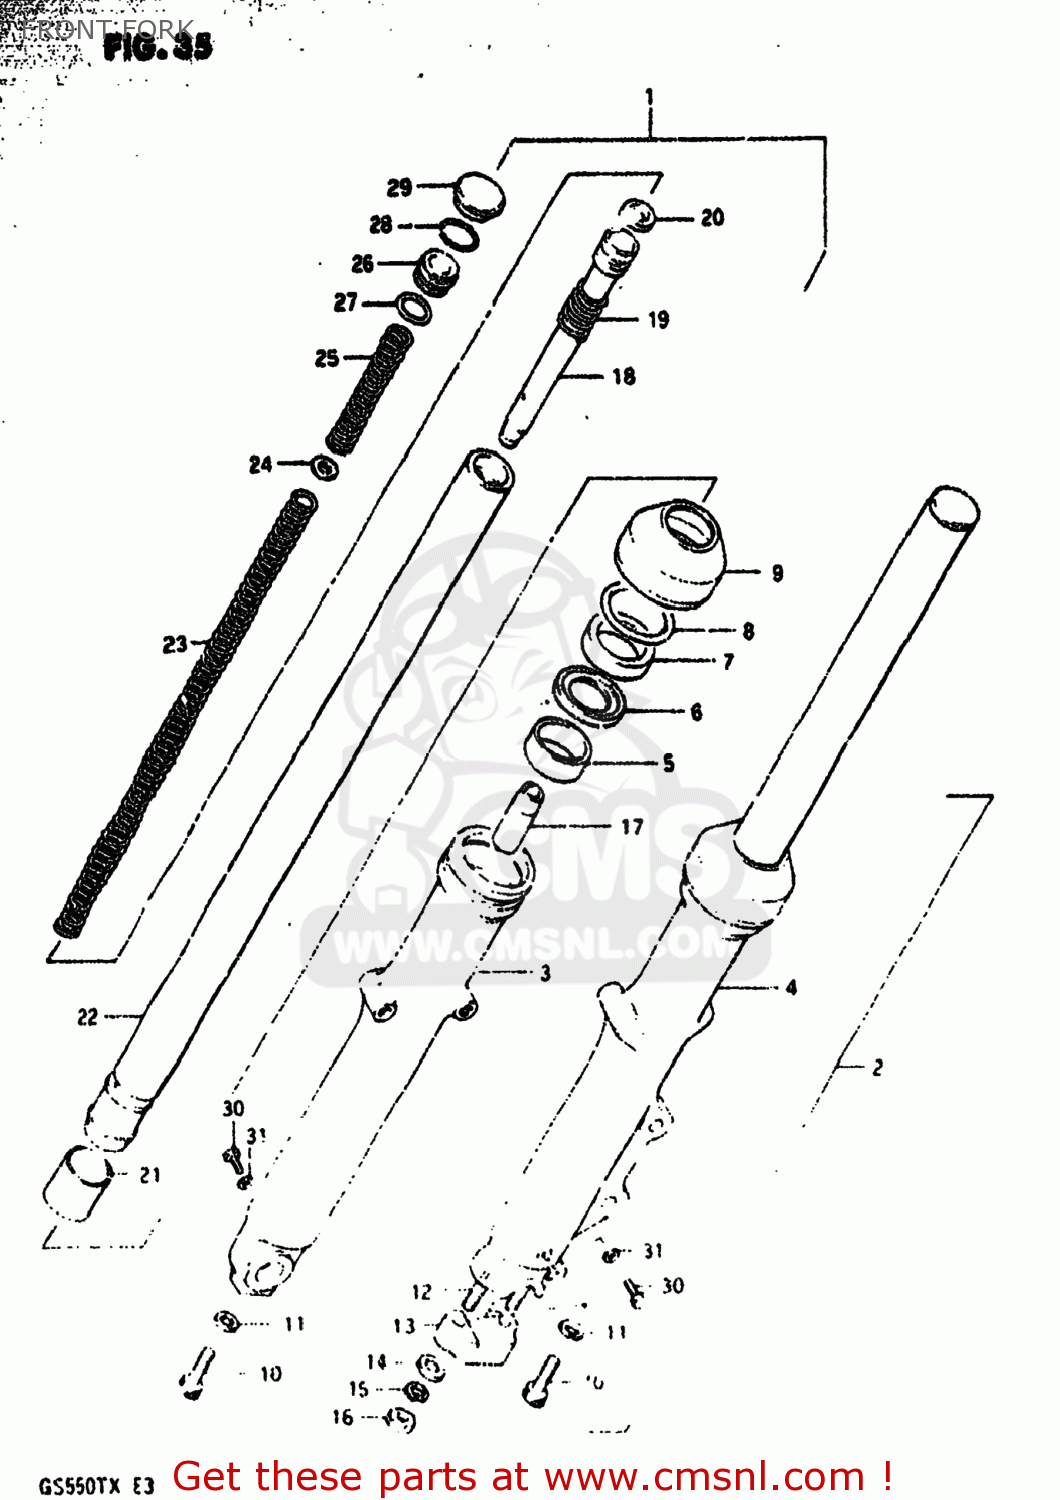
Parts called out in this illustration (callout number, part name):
1	DAMPER ASSEMBLY,RIGHT
2	DAMPER ASSEMBLY,LEFT
3	TUBE,OUTER,RIGHT
4	TUBE,FORK,LEFT,OUTER
5	BUSH,GUIDE
6	SPACER,SEAL
7	OIL SEAL,FRONT FORK
8	CIRCLIP,FORK OIL SEAL
9	BOOT
10	BOLT(8X27)
11	GASKET (NAS)
12	STUD 8X25
13	HOLDER,AXLE
14	WASHER
15	LOCK WASHER
16	NUT
17	PIECE,OIL LOCK
18	CYLINDER,FRONT FORK
19	SPRING,FORK REBOUND
20	RING
21	PISTON
22	TUBE,FORK,INNER
23	SPRING,FRONT FORK
24	WASHER,SPRING
25	SPRING
26	SPRING SEAT B
27	O-RING
28	RING,STOPPER
29	CAP
30	BOLT
31	GASKET,DRAIN,PLUG (NAS)
